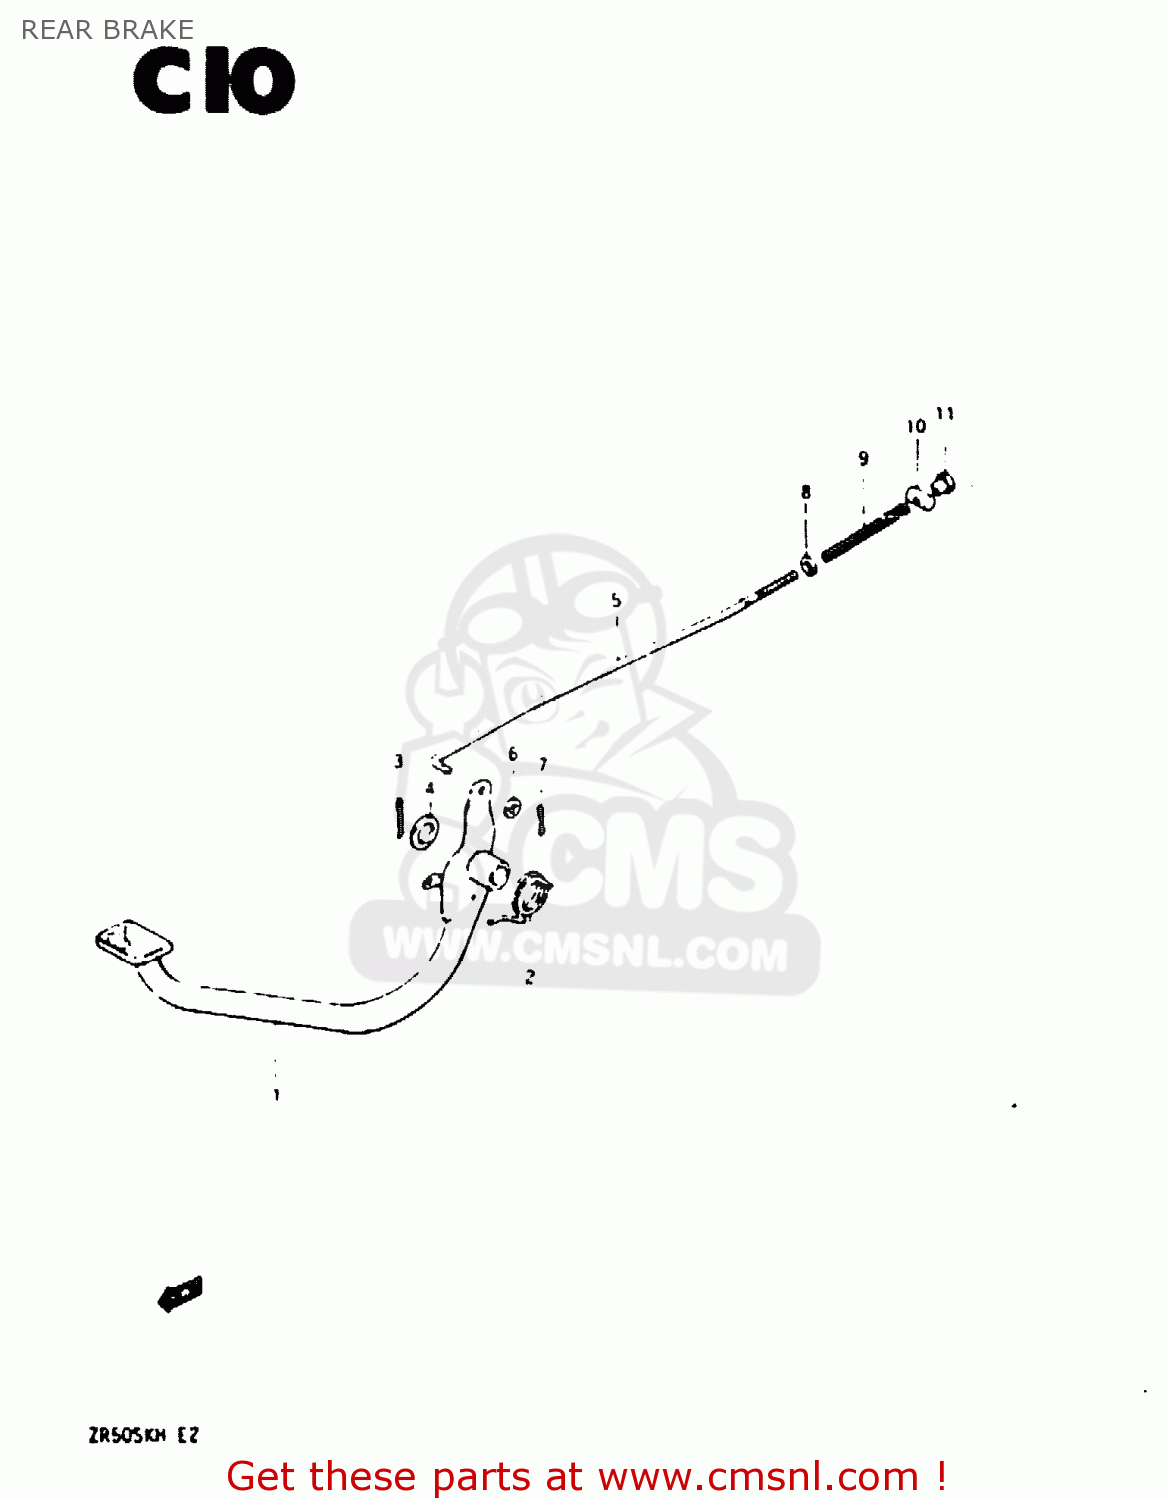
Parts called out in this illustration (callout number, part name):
1	PEDAL, BRAKE
2	SPRING
3	COTTER PIN
4	WASHER(15.5X26X2.3)
5	ROD ASSY,RR BRAKE
6	WASHER
7	PIN 20X20
8	WASHER
9	SPRING
10	PIN(11X18)
11	NUT (6MM)
